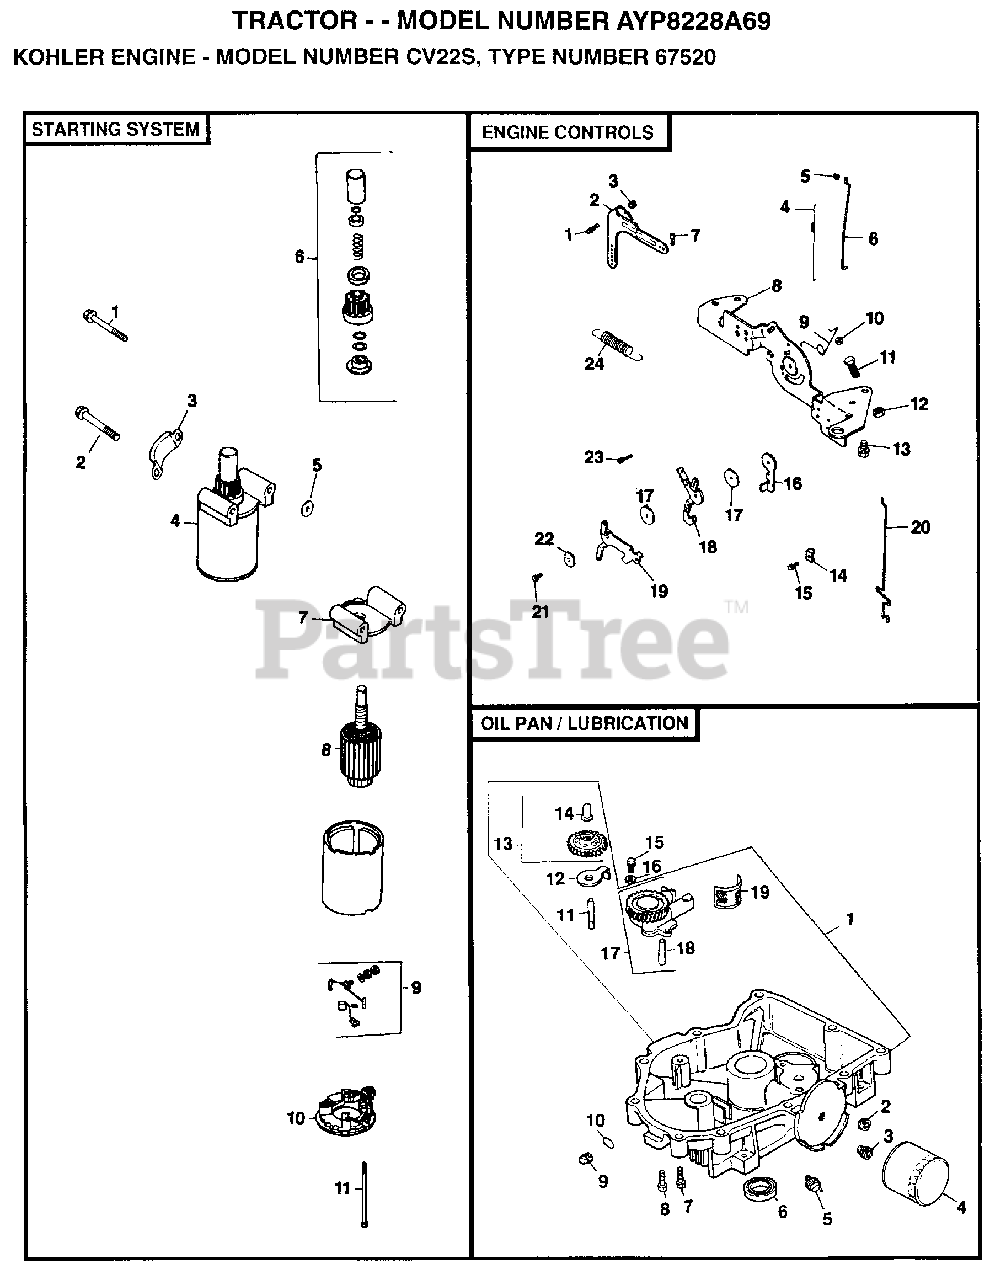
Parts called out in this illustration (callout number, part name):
1	OIL PAN ASSEMBLY
1	SCREW, GOVERNOR ARM
2	PLUG
3	NIPPLE, OIL FILTER
3	NUT
5	OIL PRESSURE SWITCH
6	KIT, DRIVE END
9	PLUG
10	LOCKNUT
11	SCREW
12	NUT
13	KIT, GOVERNOR GEAR WITH PIN
13	SCREW
15	SCREW
16	WASHER
17	OIL PUMP ASSEMBLY
21	SCREW
23	SCREW
